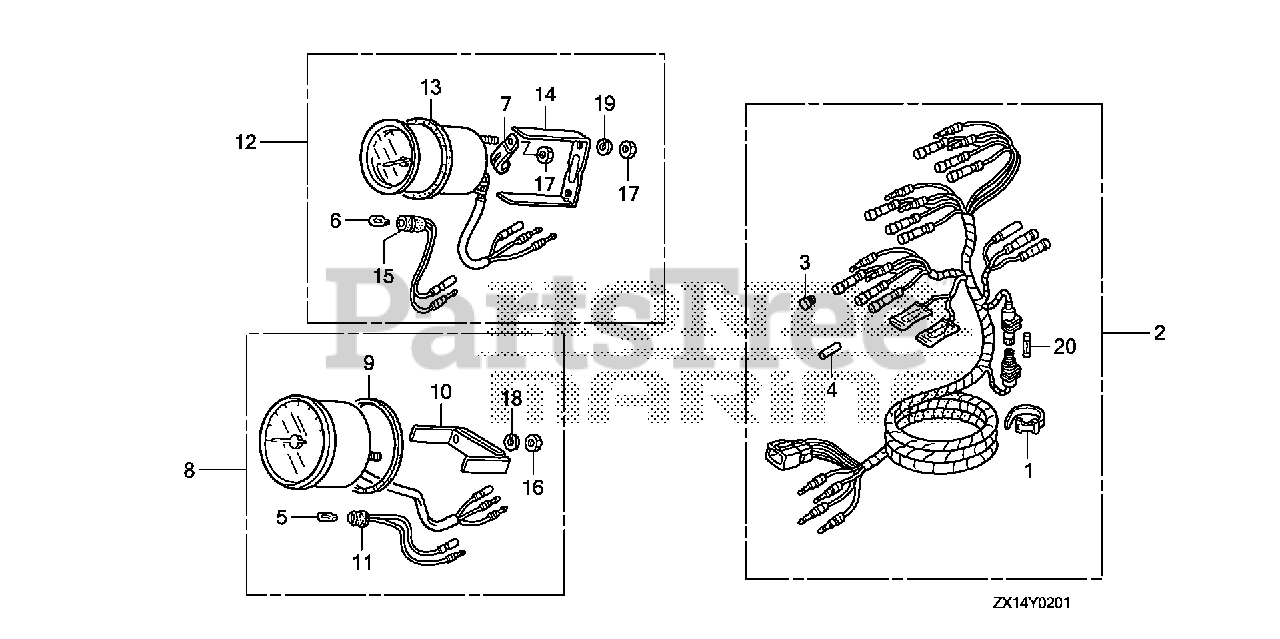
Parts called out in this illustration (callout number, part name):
1	BAND B1, CABLE Use up to Frame SN 1001879.
2	HARNESS ASSY., METER (A)
3	PLUG, CONNECTOR (INNER) (TROLLING CONTROL)
4	PLUG, CONNECTOR (OUTER) (ENGINE NO.)
5	BULB, WEDGE BASE (T10) (12V 1.7W) (STANLEY)
6	BULB, WEDGE BASE (12V1.7W) (TOSHIBA)
7	CLAMP
8	TACHOMETER ASSY.
9	GASKET
10	BRACKET (TO 1015209) (FROM 1015210)
11	SOCKET (TO 1015209) (FROM 1015210)
12	METER ASSY., TRIM
13	GASKET (TO 1015209) (FROM 1015210)
14	BRACKET (TO 1015209) (FROM 1015210)
15	SOCKET (TO 1015209) (FROM 1015210)
16	NUT, HEX. (5MM)
17	NUT, HEX. (4MM)
18	WASHER, SPRING (5MM)
19	WASHER, SPRING (4MM)
20	FUSE A (10A)
